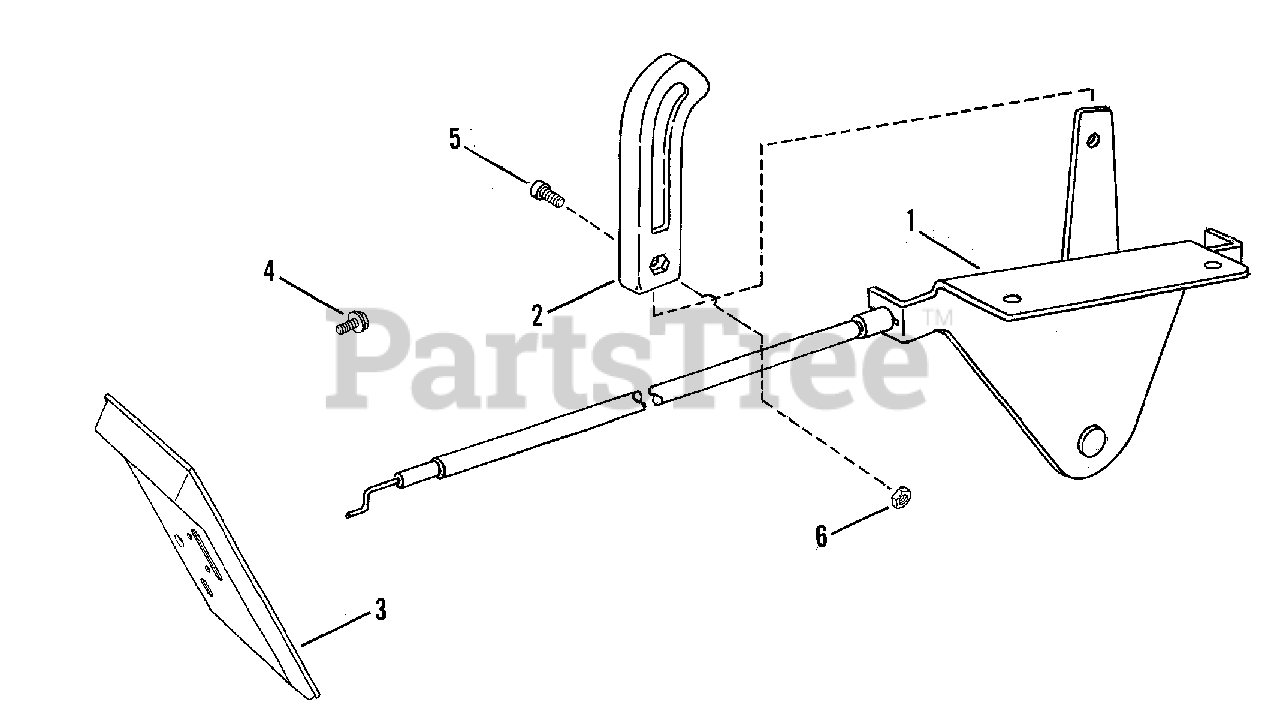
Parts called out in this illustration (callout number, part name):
1	CONTROL, Throttle
2	KNOB, Throttle Control
3	COVER, Dash Panel (Electric Start)
4	SCREW, #10-24x1/2" Hex Flange Self-Tapping
5	SCREW, #8-32x3/8" Rec. Fill. Hd.
6	NUT, #8-32 Hex
